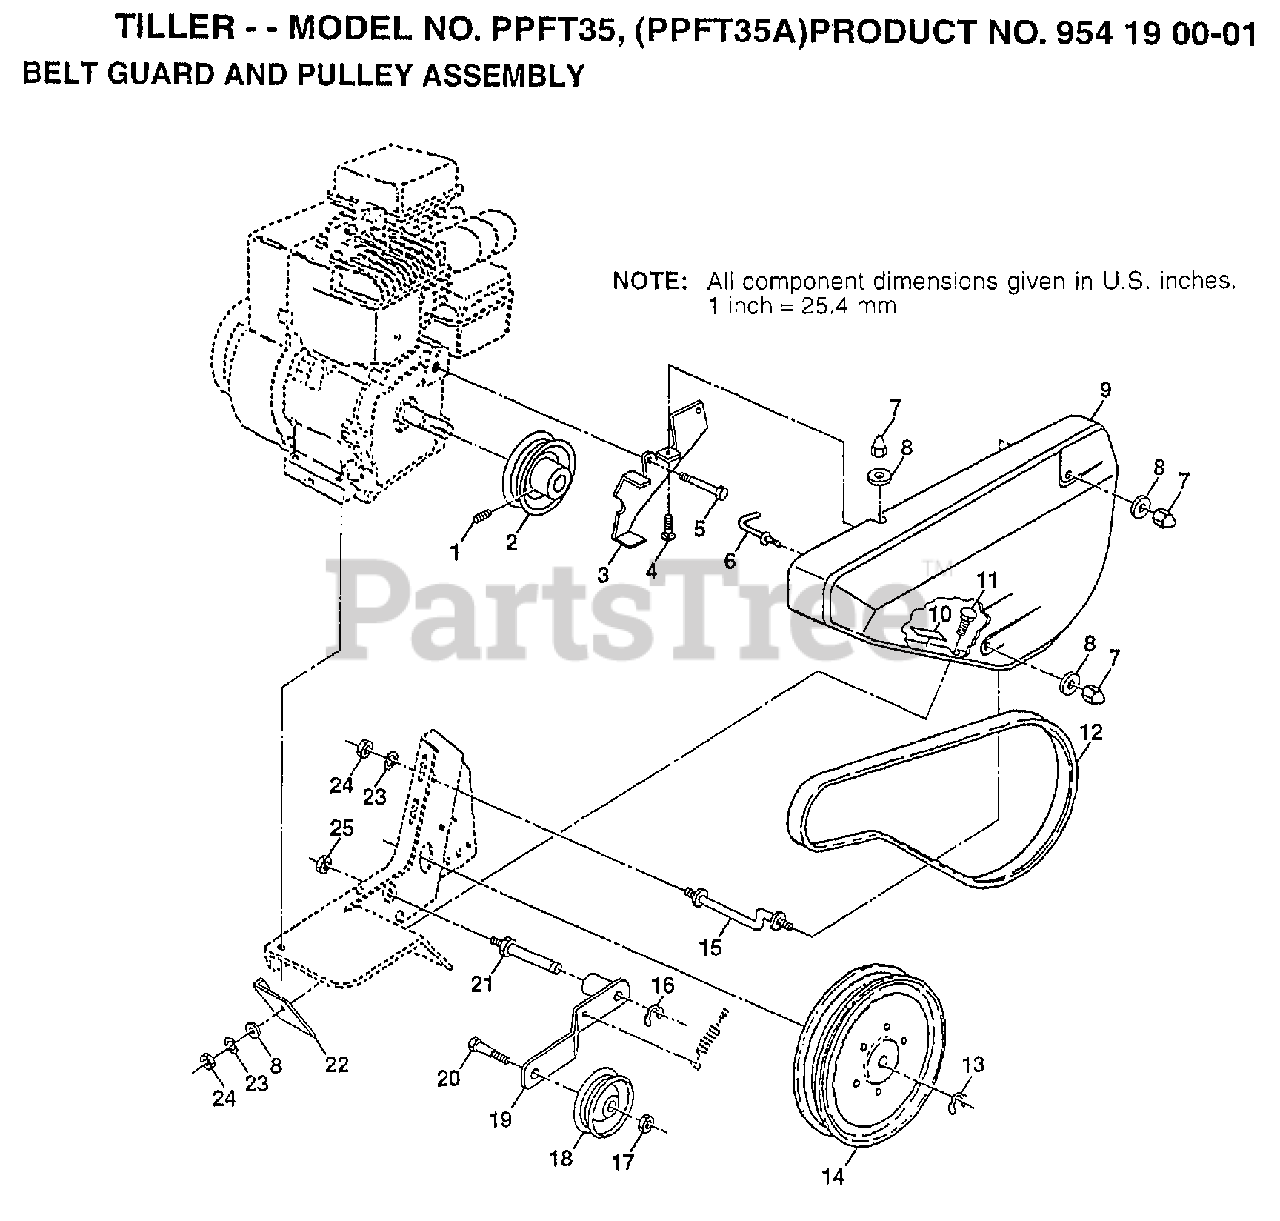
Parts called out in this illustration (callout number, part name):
1	SCREW, SET FORGED SOCKET, HEADLESS 5/16-18X3/8
2	ENGINE PULLEY
4	BOLT, CARRIAGE 1/4-20X3/4
5	BOLT, HEX 1/2-20X3/4
8	WASHER 9/32 X 5/8 X 16 GA.
11	BOLT, CARRIAGE 1/4-20 X 3/4
13	RING, RETAINER
15	BELT GUARD BOLT
17	NUT HEX JAM 3/8-16 UNC
20	BOLT, HEX 3/8-16 X 1-1/4
23	WASHER, LOCK 1/4
24	NUT, HEX 1/4-20
25	NUT, HEX, JAM 5/16-18
